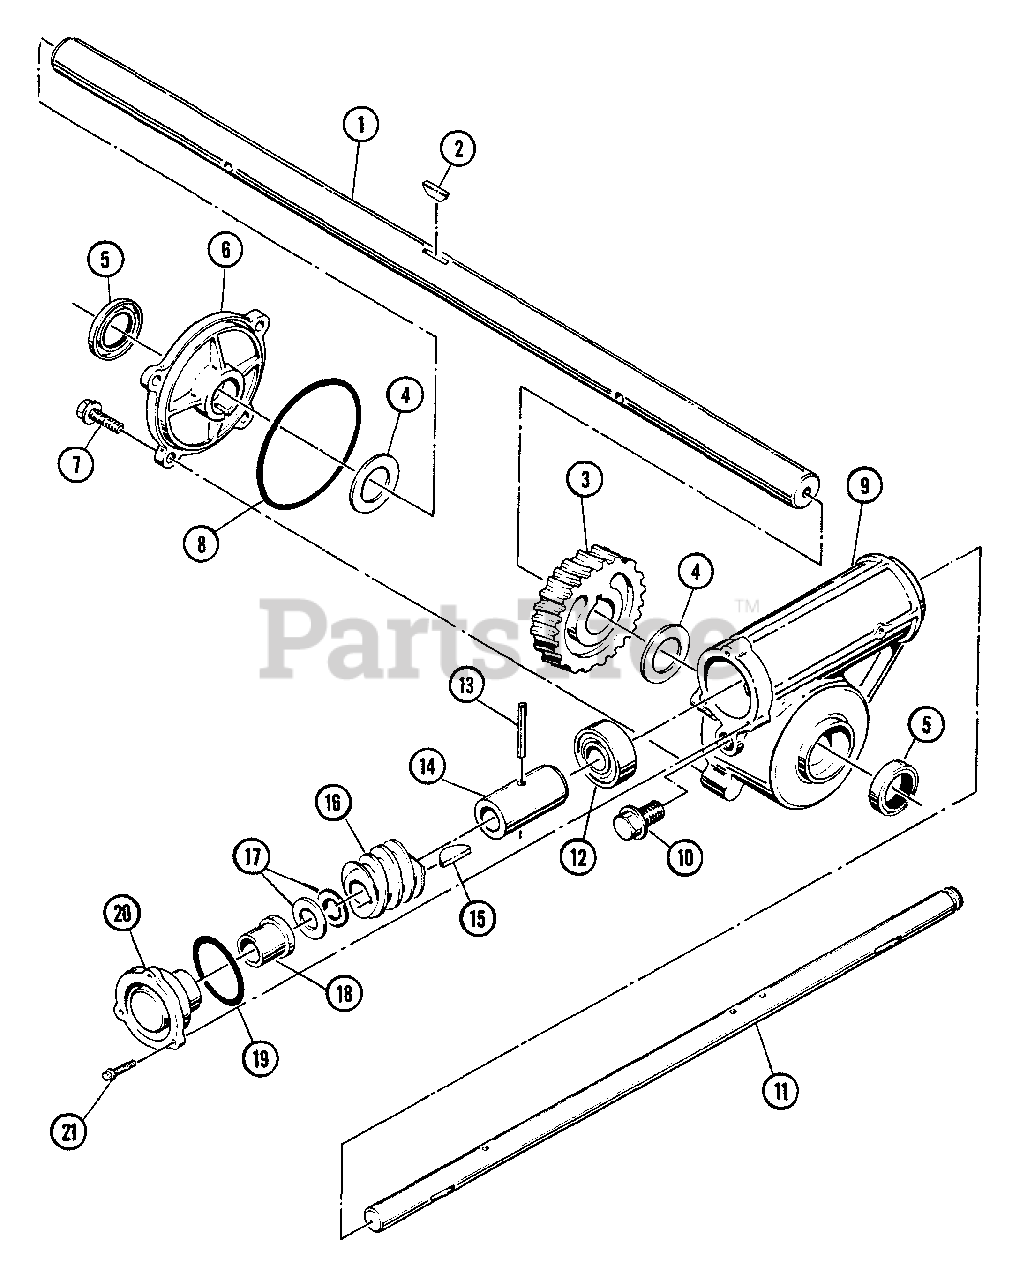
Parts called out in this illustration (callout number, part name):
1	SHAFT, Auger - 23" Units
2	KEY, #A Woodruff
3	GEAR, Worm
4	WASHER, Thrust
5	SEAL, Oil
6	COVER, Gear Case
7	SCREW, 1/4-20 x 3/4" Hex Washer Head Self-Tap
8	O-RING, Case Cover
9	CASE, Gear
10	SCREW, 3/8-16 x 1/2" Hex Head Cap
11	SHAFT, Impeller (Bushing Type - Serial Prefix 03 only)
12	BEARING, Impeller Shaft
13	PIN, 1/4 x 1-1/2" Roll
14	SPACER, Gear - Bearing
15	KEY, 3/16 x 7/8" Woodruff
16	GEAR, Rolled Worm
17	WASHER, Thrust
18	BUSHING, Impeller Shaft
19	O-RING, Case Cap
20	CAP, Case
21	SCREW, #10-24 x 5/8" Hex Washer Self-Tap
